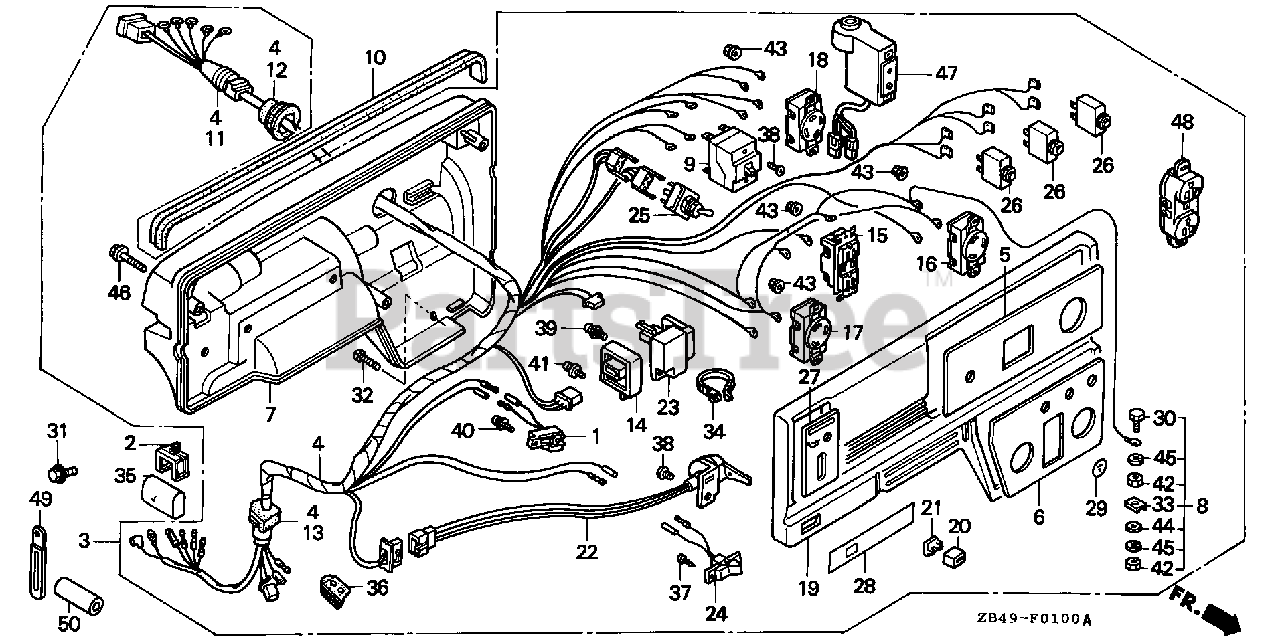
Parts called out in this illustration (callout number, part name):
3	BOX ASSY., CONTROL *R8* (BRIGHT RED)
3	BOX ASSY., CONTROL *R280* (POWER RED)
4	WIRE HARNESS ASSY.
5	MARK, SWITCH PANEL
6	MARK, A.C. OUT
7	CASE, CONTROL *R280* (POWER RED)
8	TERMINAL SET, GROUND
9	PROTECTOR, CIRCUIT (13A)
10	RUBBER, CONTROL
11	GROMMET, A.C. WIRE
12	GROMMET, MAIN WIRE
13	GROMMET, SWITCH WIRE
14	DIODE ASSY.
16	RECEPTACLE (20A/125V) (NOT AVAILABLE)
17	RECEPTACLE (30A/125V)
18	RECEPTACLE (20A-125/250V) (MATSUSHITA) (NOT AVAILABLE)
19	PANEL, CONTROL *R280* (POWER RED)
20	KNOB, PETCOCK LEVER
21	BUSH, CONTROL KNOB
22	SWITCH ASSY., ENGINE STOP
23	THROTTLE UNIT, AUTO (SAWAFUJI)
24	SWITCH, AUTO THROTTLE
25	SWITCH ASSY., VOLT CHANGE
26	PROTECTOR, CIRCUIT (20A)
27	MARK, ENGINE SWITCH
28	MARK, AUTO-THROTTLE
29	MARK, GROUND
30	BOLT, HEX. (6X28)
31	BOLT, FLANGE (6X12) (CT200)
32	SCREW, GLOVE BOX
33	RETAINER (6MM)
34	TIE, CABLE (NATURAL 225X5.0)
36	GROMMET, TUBE
37	SCREW, PAN (3X6)
38	SCREW, PAN (4X6)
39	SCREW-WASHER (5X12)
41	SCREW-WASHER (4X12)
42	NUT, HEX. (6MM)
43	NUT, FLANGE (4MM)
44	WASHER, PLAIN (6MM)
45	WASHER, SPRING (6MM)
46	BOLT, FLANGE (6X40)
47	RELAY ASSY. (GFCI)
48	RECEPTACLE (20A/125V) (MATSUSHITA)
49	CLIP, WIRE HARNESS
50	TUBE, CORD
